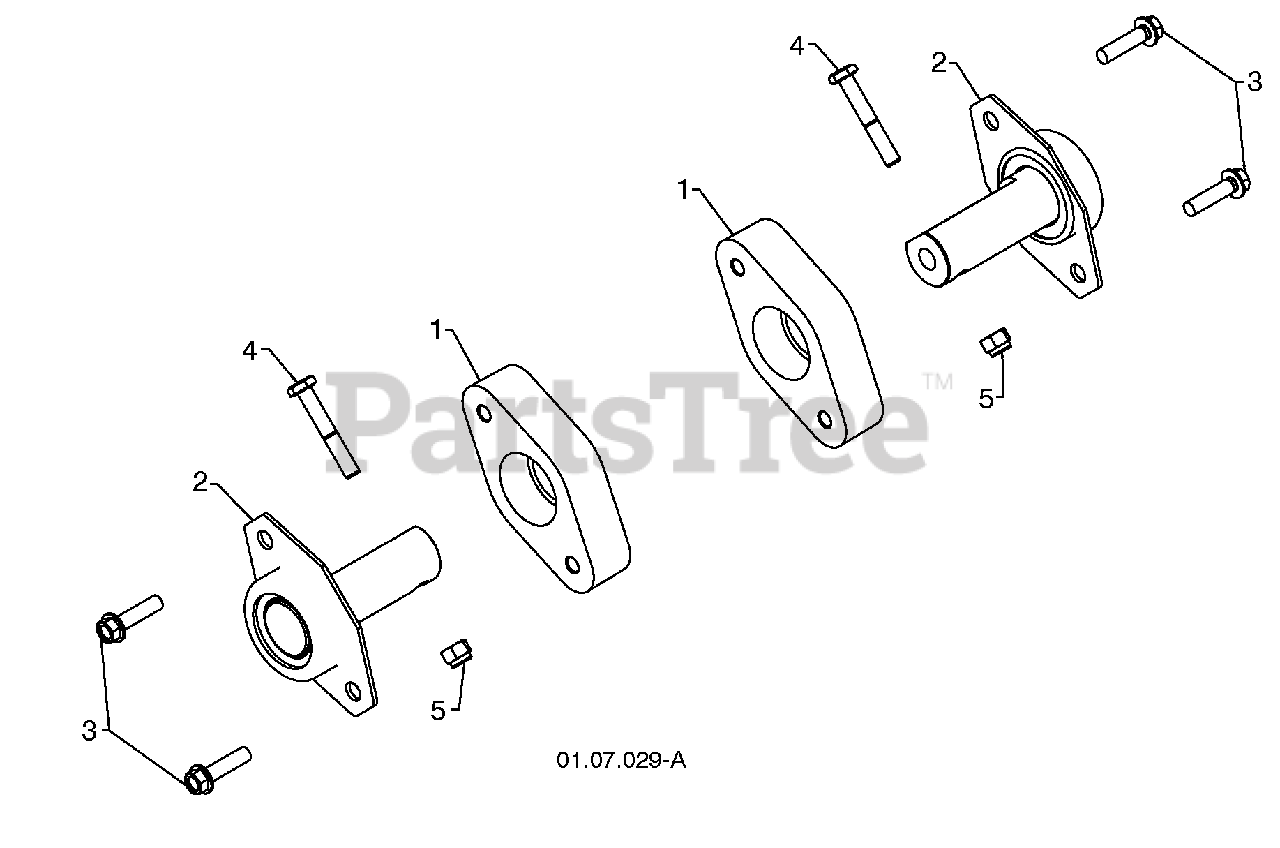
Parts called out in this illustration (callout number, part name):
1	PLASTIC RETAINER
2	AUGER BALL BEARING
3	SCREW 5/16-18 X 1.00
4	SCREW 1/4-20 X .625
5	NUT 1/4-20
